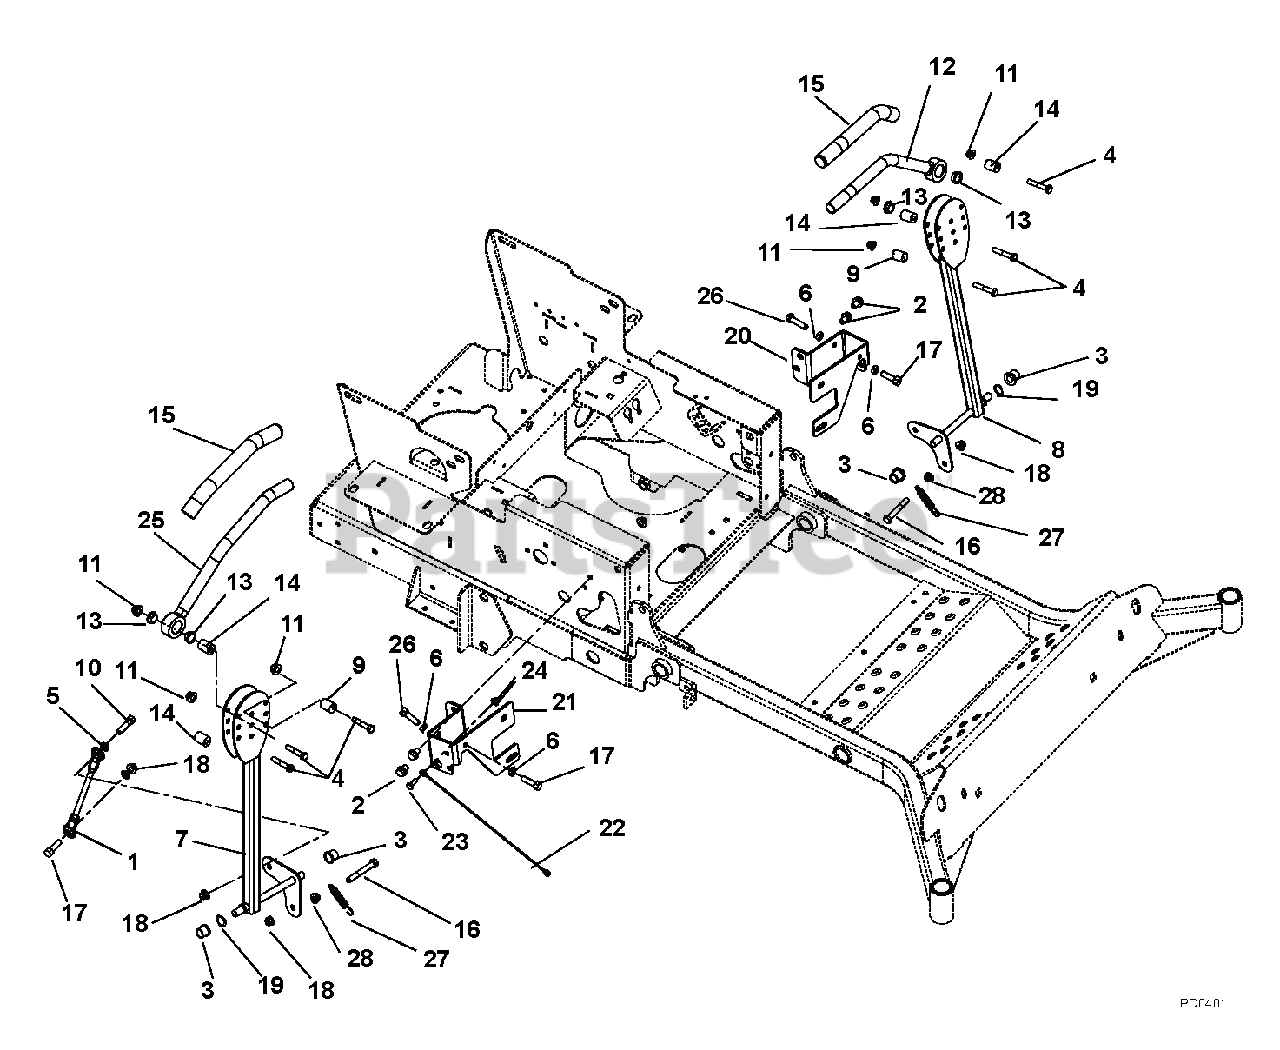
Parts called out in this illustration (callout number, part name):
1	ASM, STEERING LINKAGE
2	@SCR-TAP .38-16X.50 HWH TR YWZ
3	BSHG-FLG .515X.750X.745X1.00NY
4	@BLT-HEX .31-18X1.75 GR5 YWZC
5	@WSHR-LK .38X.094 REG YWZC
6	NUT-HEX-JAM .375-16 YWZC
7	WMT, RH CONTROL
8	WMT, LH CONTROL
9	BSHG, ECCENTRIC .328X.750X.970
10	@BLT-HEX .38-16X1.50 GR5 YWZC
11	@NUT-LK-NYL-FLG .31-18 YWZC
12	HANDLE WLDMT LH
13	BSHG-FLG .762X1.48X.44 NYL
14	SPACER .328 X .76 X 1.01
15	GRIP, HANDLEBAR
16	@BLT-HEX .38-16X2.75 GR5 YWZC
17	@BLT-HEX .38-16X1.25 GR5 YWZC
18	@NUT-LK-NYL-FLG .38-16 YWZC
19	WAVE WASHER .640X.875X.125FH
20	BRKT, LH STEERING STOP
21	RH STEERING STOP BRKT - BLK
22	CABLE, 12.0 LANYARD, NYLON
23	@BLT-HEX .25-20X.75 GR5 YWZC
24	@NUT-LK-NYL-FLG .25-20 YWZC
25	WLDMT, RH HANDLE
26	@BLT-HEX .38-16X.75 GR5 YWZC
27	SPRING,EXT,.061X.50X3.0
28	@NUT-SPNLK-FLG .375-16 YWZC
